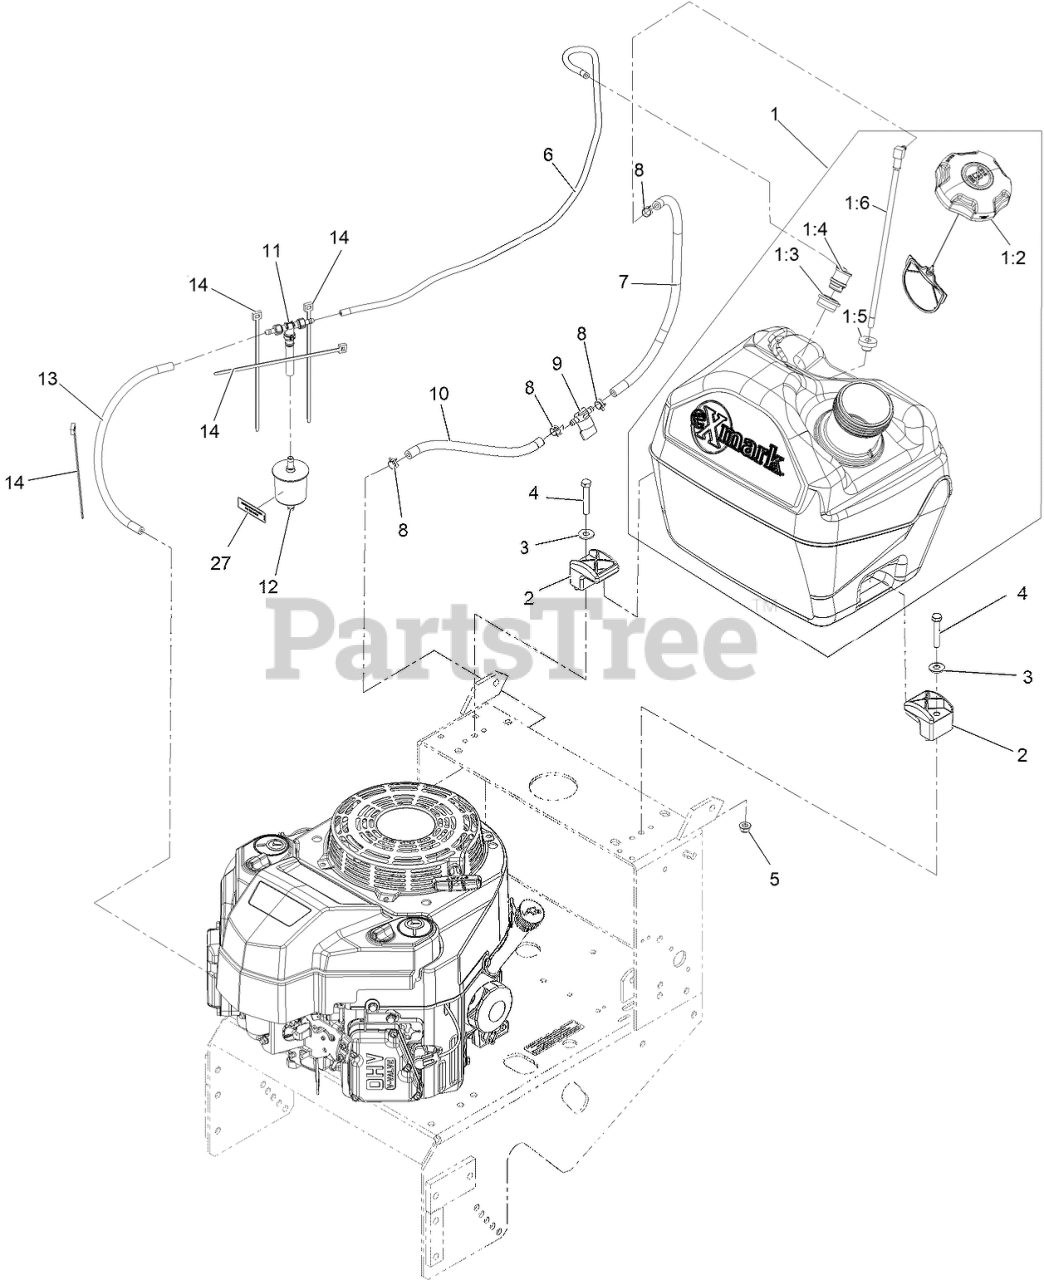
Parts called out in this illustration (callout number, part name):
1	ASM, FUEL TANK 5 GAL
1:2	CAP-FUEL, RATCHETING
1:3	GROMMET
1:4	VALVE-VENT, FUEL
1:5	BUSHING
1:6	FITTING, FUEL W/LINE AND SCREEN
3	WASHER-FLAT
4	SCREW-HH
5	NUT-HF, NI
6	HOSE-EMISSIONS
7	HOSE-FUEL
8	CLAMP-HOSE
9	VALVE-FUEL
10	HOSE-FUEL
11	TEE AND CHECK
12	FILTER-FUEL
13	HOSE-FUEL
14	TIE-CABLE
27	DECAL-FILTER, EMISSIONS
